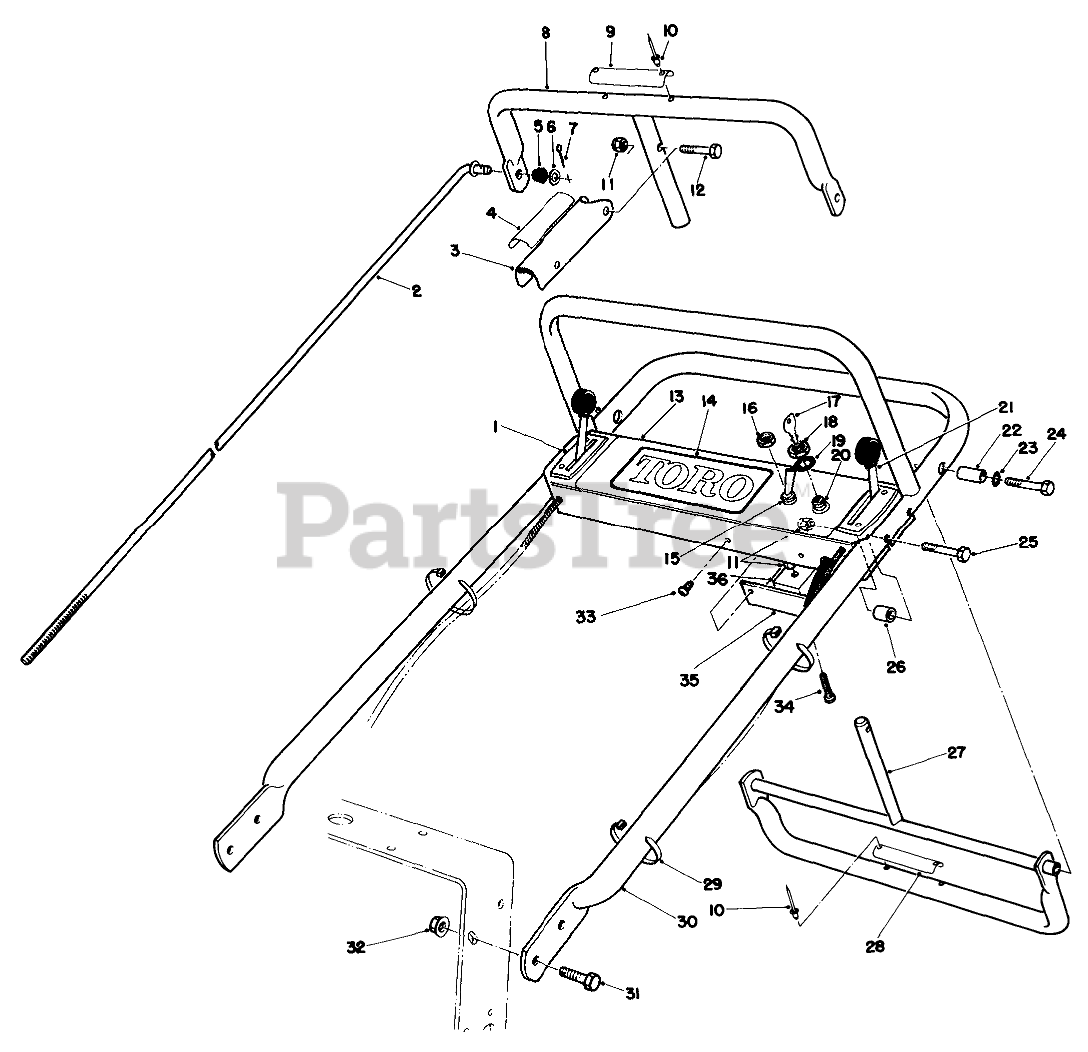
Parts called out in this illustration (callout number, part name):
1	CHOKE CONTROL
2	ROD-CONTROL
3	Lever-Parking Brake
4	DECAL-LEVER, PARKING
5	GROMMET-RUBBER
6	WASHER-PLAIN
7	PIN-COTTER
8	Bar-Control
9	DECAL-CONTROL BAR
10	RIVET-BLIND
11	NUT-LOCK, NI
12	SCREW-SHH
13	Panel-Control
14	RECOIL PANEL DECAL
15	Switch
16	NUT
17	Key
18	NUT-HH
19	WASHER-TOOTH, INTERNAL
20	Ignition Switch (Incl. Ref. #17-19)
21	THROTTLE CONTROL
22	PIVOT-SPACER
23	WASHER-LOCK
24	SCREW-HH
25	SCREW-SHH
26	SPACER
27	Control-Pivot
28	DECAL-REVERSE HANDLE
29	TIE-CABLE
30	HANDLE-UPPER
31	SCREW-HHF
32	NUT-HF
33	SCREW-HWHTF
34	SCREW-HWH
35	PANEL-BOTTOM
36	RECTIFIER-BRIDGE
